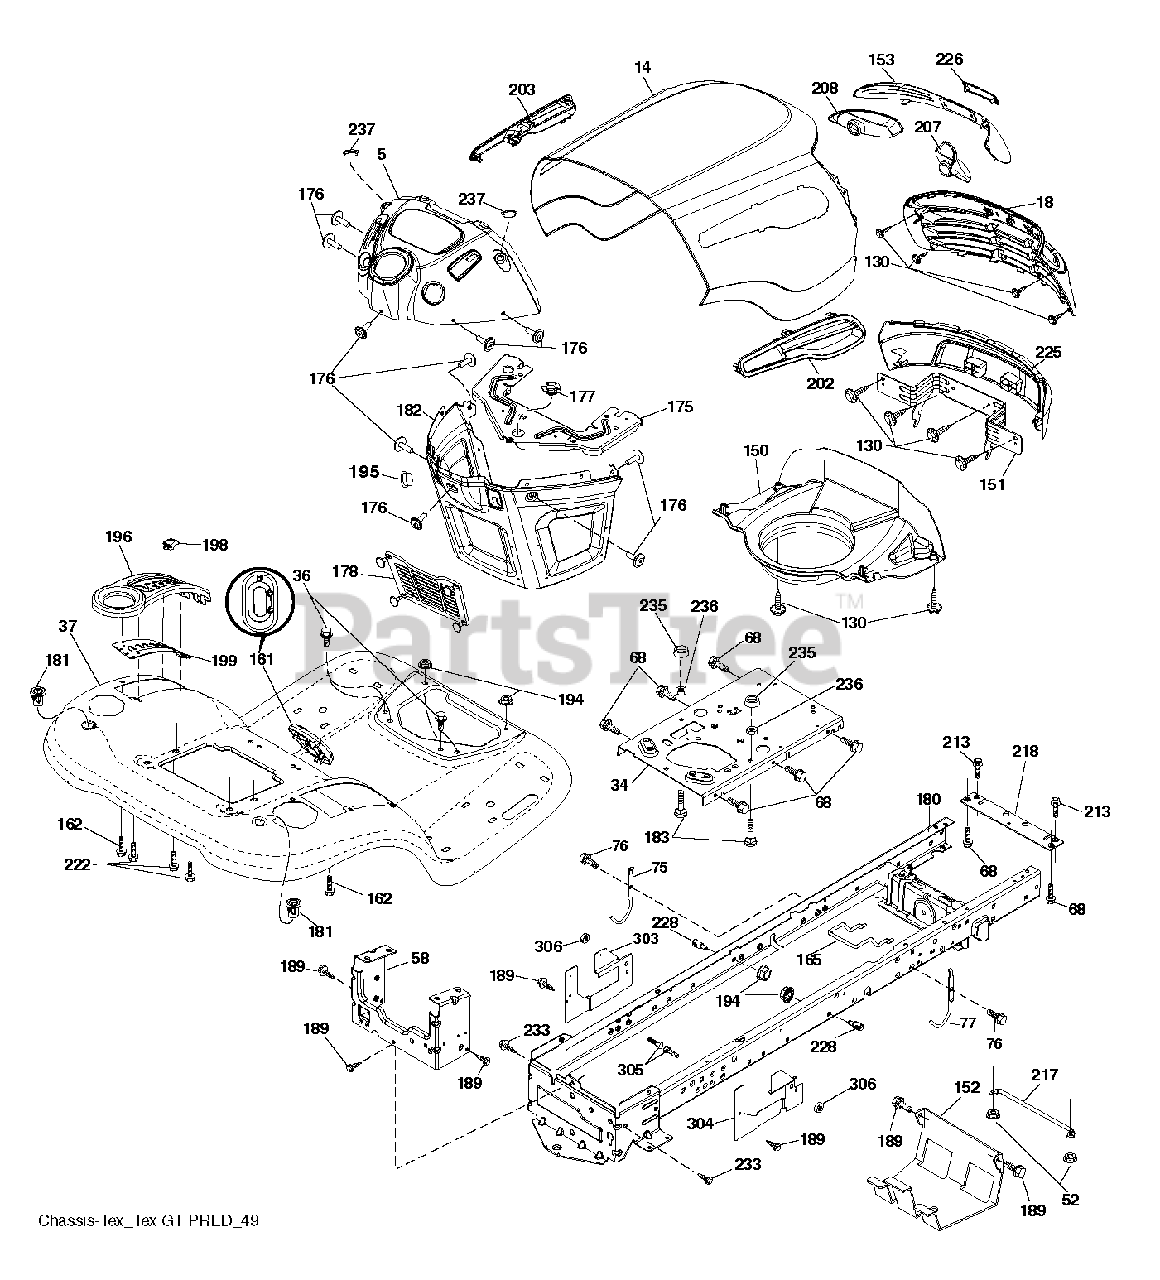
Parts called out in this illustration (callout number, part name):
36	SCREW 5/16"
52	LOCKNUT
58	DRAWBAR.UPPER.2PC,LRG.FENDER
75	ROD UPSTOP
76	SCREW 3/8-16X1
77	ROD UPSTOP
130	SCREW.#10 X 0.750.BOS THREAD
152	SHIELD BROWNING
161	CONSOLE.FUEL.WINDOW.STGT.BLACK
162	SCREW.HI-LO.CONSOLE
165	SUPPORT.TANK.REAR.W/TE
175	PLATE.CROSSMEMBER.HUSQ
176	SCREW.#10-24X5/8.RN.QU
177	BUSHING,STEERING
178	CARGO.ASM.NET.TXGT.W/C
180	CHASS.WLDMNT.TL.12GA/2P.48/54
181	FEND/FTRST.PCH.CPH.NFW
182	DASH.LOWER.COMMON.12V.ADAPTOR
183	BOLT.5/16-18X1-1/4 FULL THD
189	SCREW
194	NUT LOCK HEX FLANGE 5/16-18
195	PLUG.HOLE.DASH.LOWER.12V.BLK
198	INDICATOR.DECK.LIFT.RED
199	PLATE DECK LIFT
213	BOLT
217	ROD.PIVOT.HOOD
218	X-PIECE.HOOD.STOP.NON/
222	SCREW.1/4-20X5/8
228	STUD.FASTNER.W/ANTI-ROTATE
233	BOLT.SHOULDER
235	SPACER FENDER
236	NUT.CENTERLOCK.5/16-
237	PLUG.MOUNT.CARGO.BLK
306	NUT LOCK FLG 3/8-16 UNC
